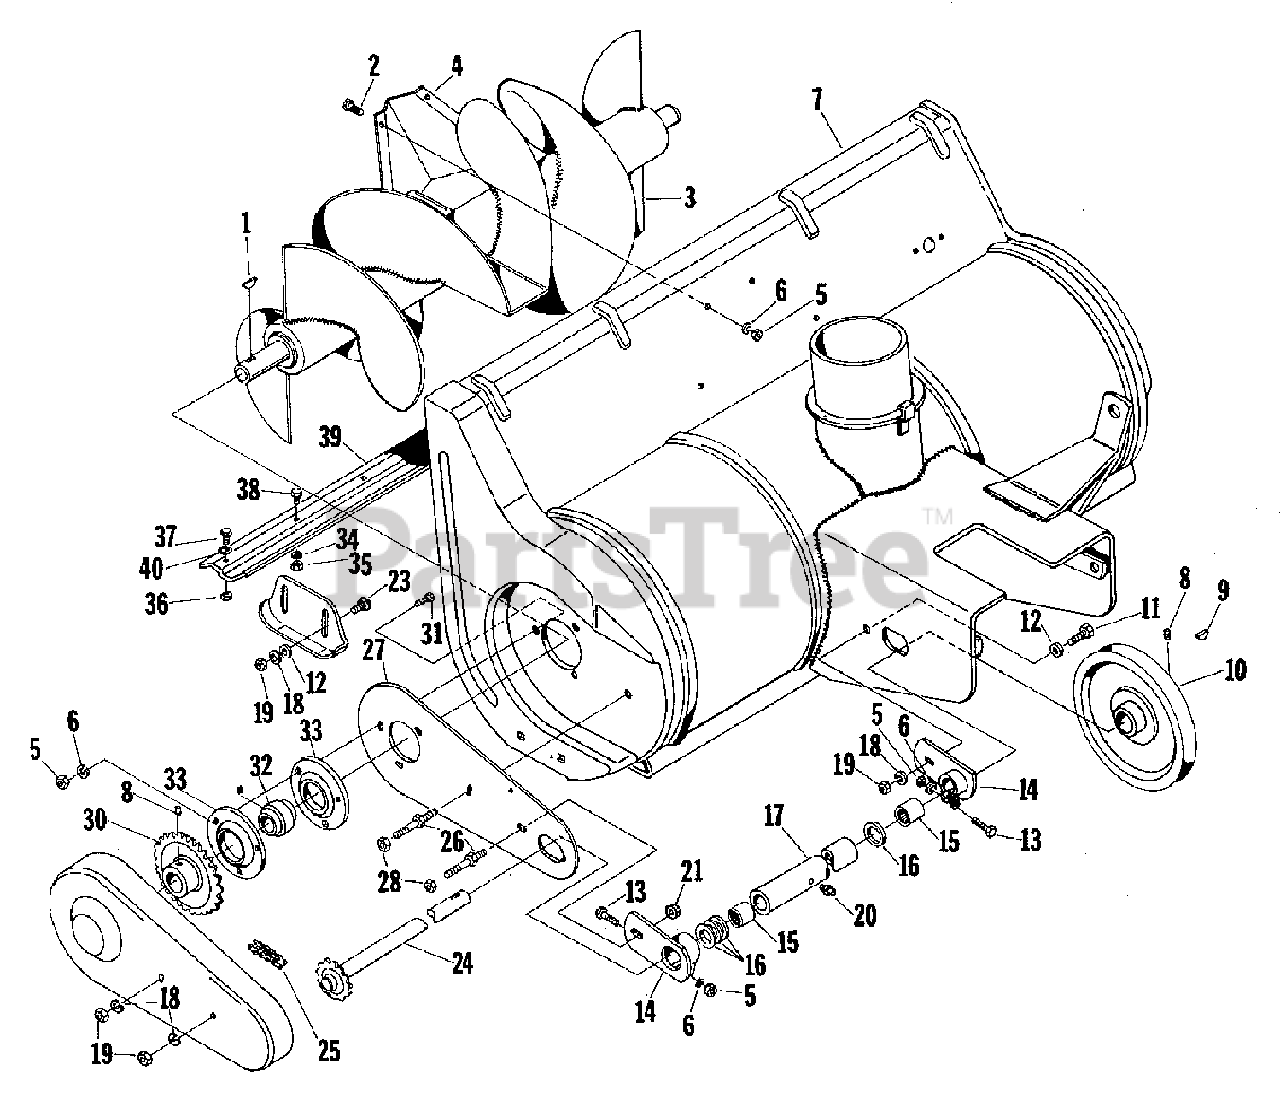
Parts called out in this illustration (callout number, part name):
2	SCREW, Hex Cap, 5/16-18 x 5/8
5	NUT, hex, 5/16-18
6	WASHER, Lock, 5/16
8	SCREW, Set, 5/16-18 x 5/16
9	KEY, Woodruff #9
10	PULLEY, Drive
11	SCREW, Hex Cap, 3/8-16 x 1
12	WASHER, Flat, 3/8
13	SCREW, Hex Cap, 5/16-18 x 1-1/2
14	CLAMP, Support Assembly
15	BEARING, Needle
16	WASHER, Lock, 3/8"
17	HOUSING, Bearing
18	WASHER, Lock, 3/8"
19	NUT, Hex, 3/8-16
20	FITTING, Grease
21	NUT, Flange, 3/8-16
23	BOLT, Carriage, 3/8-16 x 3/4
28	NUT, Hex Lock, 3/8-16
29	GUARD, Chain
30	SPROCKET, Rotor
31	SCREW, Hex Cap, 5/16-18 x 3/4
32	CARTRIDGE, Bearing w/Setscrew
33	FLANGE, Bearing
34	NUT, hex, 1/4-20
35	WASHER, Lock, 1/4"
36	NUT, Hex Lock, 5/16-18
37	SCREW, Hex Cap, 5/16-18 x 5/8
38	SCREW, Hex Cap, 1/4-20 x 5/8
39	SCRAPER, Body
